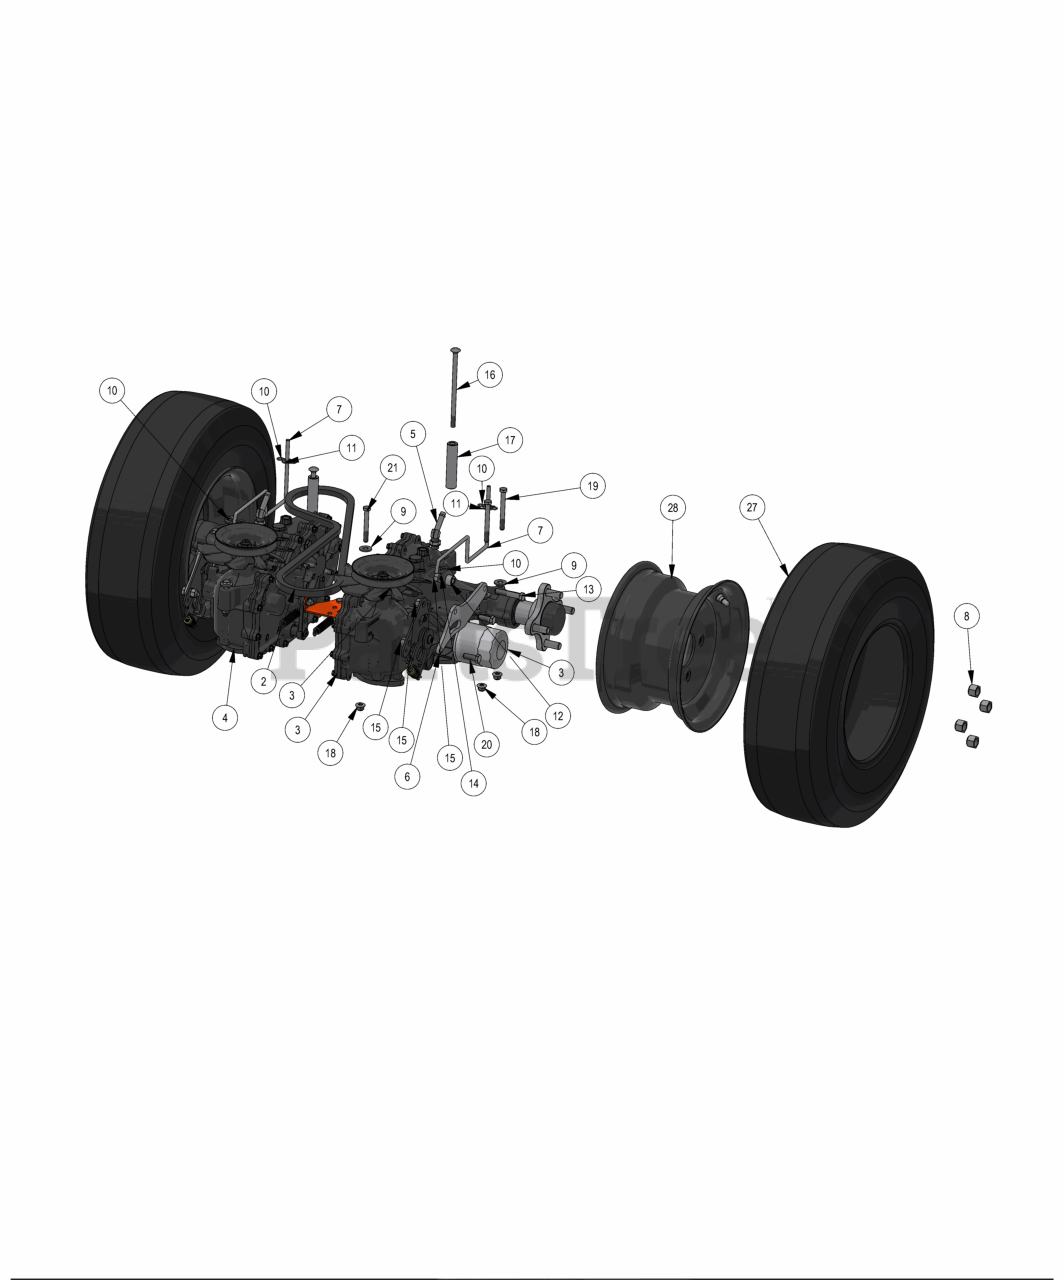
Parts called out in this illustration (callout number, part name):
1	2020 36" Brake Bracket 2020 36" Stand On
2	2019 Renegade Pump Belt
3	ZT Transaxle Left 3100
4	ZT Transaxle Right 3100
5	ZT Fitting, 3/8 x 3/8 45 Degree, 4603-6-6
6	Control Arm Plate 2019 Stand On
7	2019 Stand On Neutral Rod
8	Acorn Lug Nut
9	5/16 USS FLAT WASHER (7/8 OD) ZINC
11	1/4 USS FLAT WASHER (3/4 OD) ZINC
12	ACS Spacer 3/4x3/8x1/2
13	3/8-16 X 2 HEX CAP SCREW (GR.5) ZINC
14	3/8 SPLIT LOCKWASHER ZINC
15	3/8-16 HEX NUT ZINC
16	5/16-18 X 6 CARRIAGE BOLT (GR.5) ZINC
17	2017 Transaxle Spacer
18	5/16" Nylock Flange Nut Zinc
19	5/16-18 X 3 HEX CAP SCREW (GR.5) ZINC
20	3/8-16 X 1 GR 5 Hex Bolts Zinc
21	5/16-18 X 2-1/2 HEX CAP SCREW (GR.5) ZINC
22	1/4-20 NYLON INSERT LOCKNUT ZINC
23	1/4-20 Nylon Insert flange Nut
24	1/4-20 X 3/4 HEX CAP SCREW (GR.5) ZINC
25	1/4-20 X 1 HEX CAP SCREW (GR.5) ZINC
26	Brake Spring
27	36" Revolt Reaper Tire
28	36" Revolt Wheel
